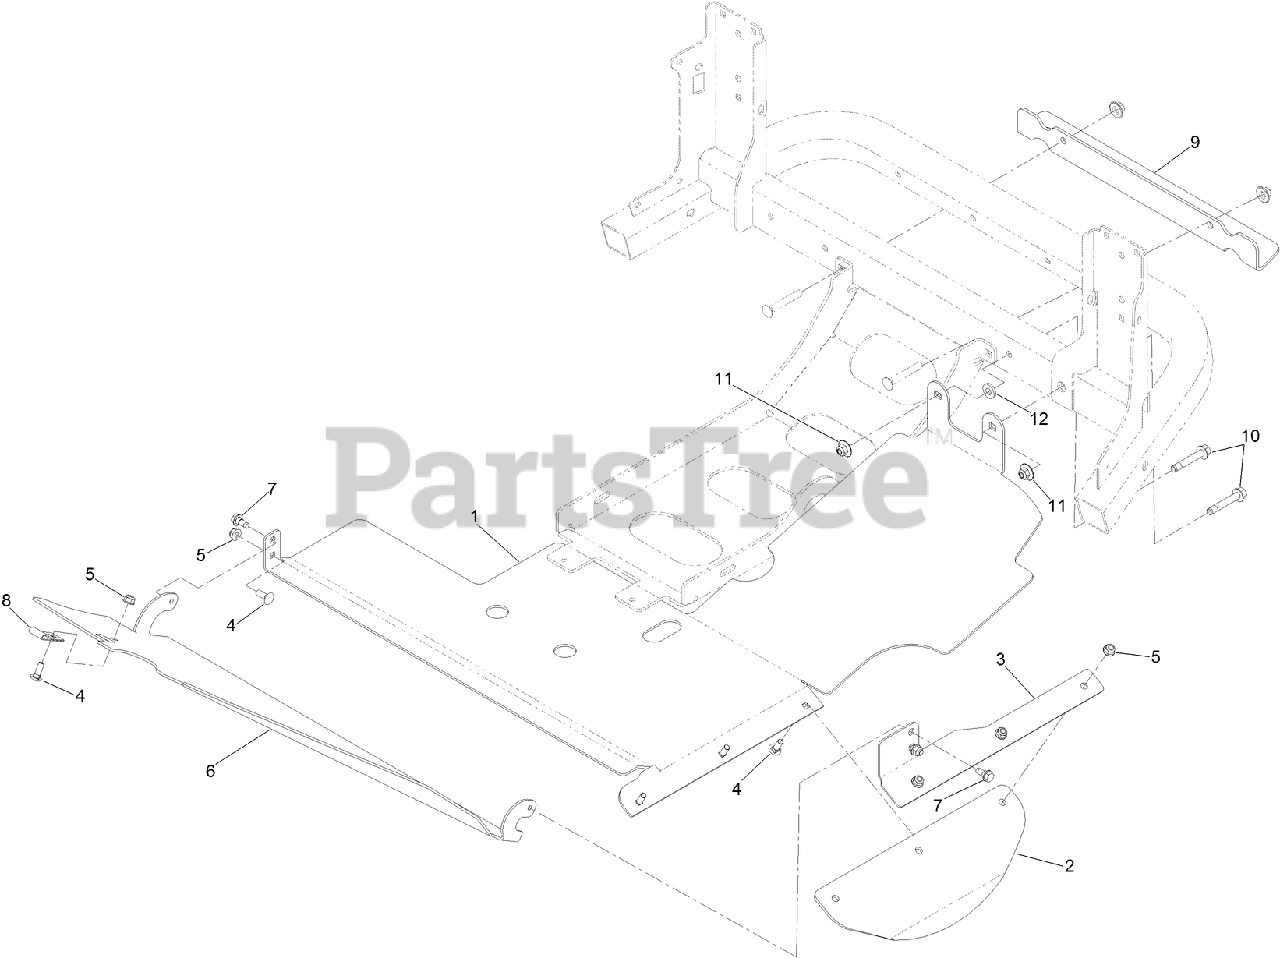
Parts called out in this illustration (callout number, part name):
1	PLATE-DISCHARGE
2	FLAP-RUBBER
3	BRACKET-FLAP, LH
4	SCREW-CARR
5	NUT-HF, NI
6	PANEL-DISCHARGE
7	SCREW-SHOULDER
8	BEARING-STRAP, NYLON
9	BRACKET-TIE DOWN
10	SCREW-HHF
11	NUT-FLANGE, NI
12	SPACER
